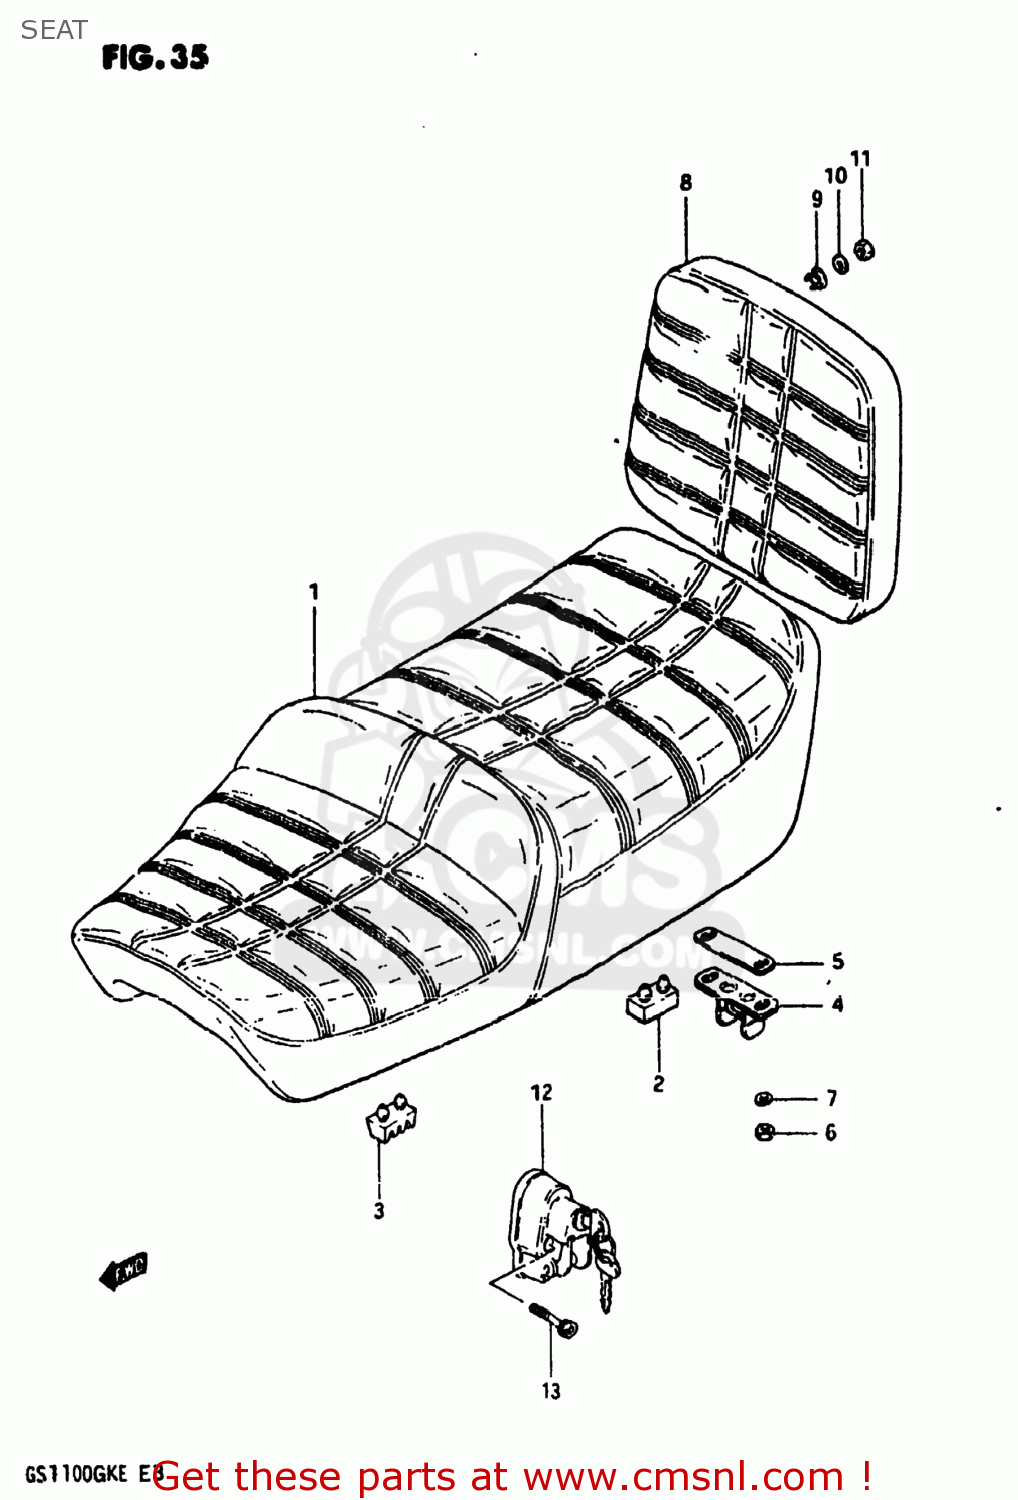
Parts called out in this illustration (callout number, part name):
1	SEAT ASSEMBLY
2	CUSHION(40X23X12.7)
3	CUSHION,SUPPORT(50X25X32)
4	STRIKER,SEAT LOCK
5	SHIM,SEAT LOCK STRIKER
6	NUT 6MM
7	LOCK WASHER
8	PAD ASSEMBLY
9	WASHER
10	LOCK WASHER
11	NUT 6MM
12	LOCK ASSY,HELMET
13	BOLT 5X25
